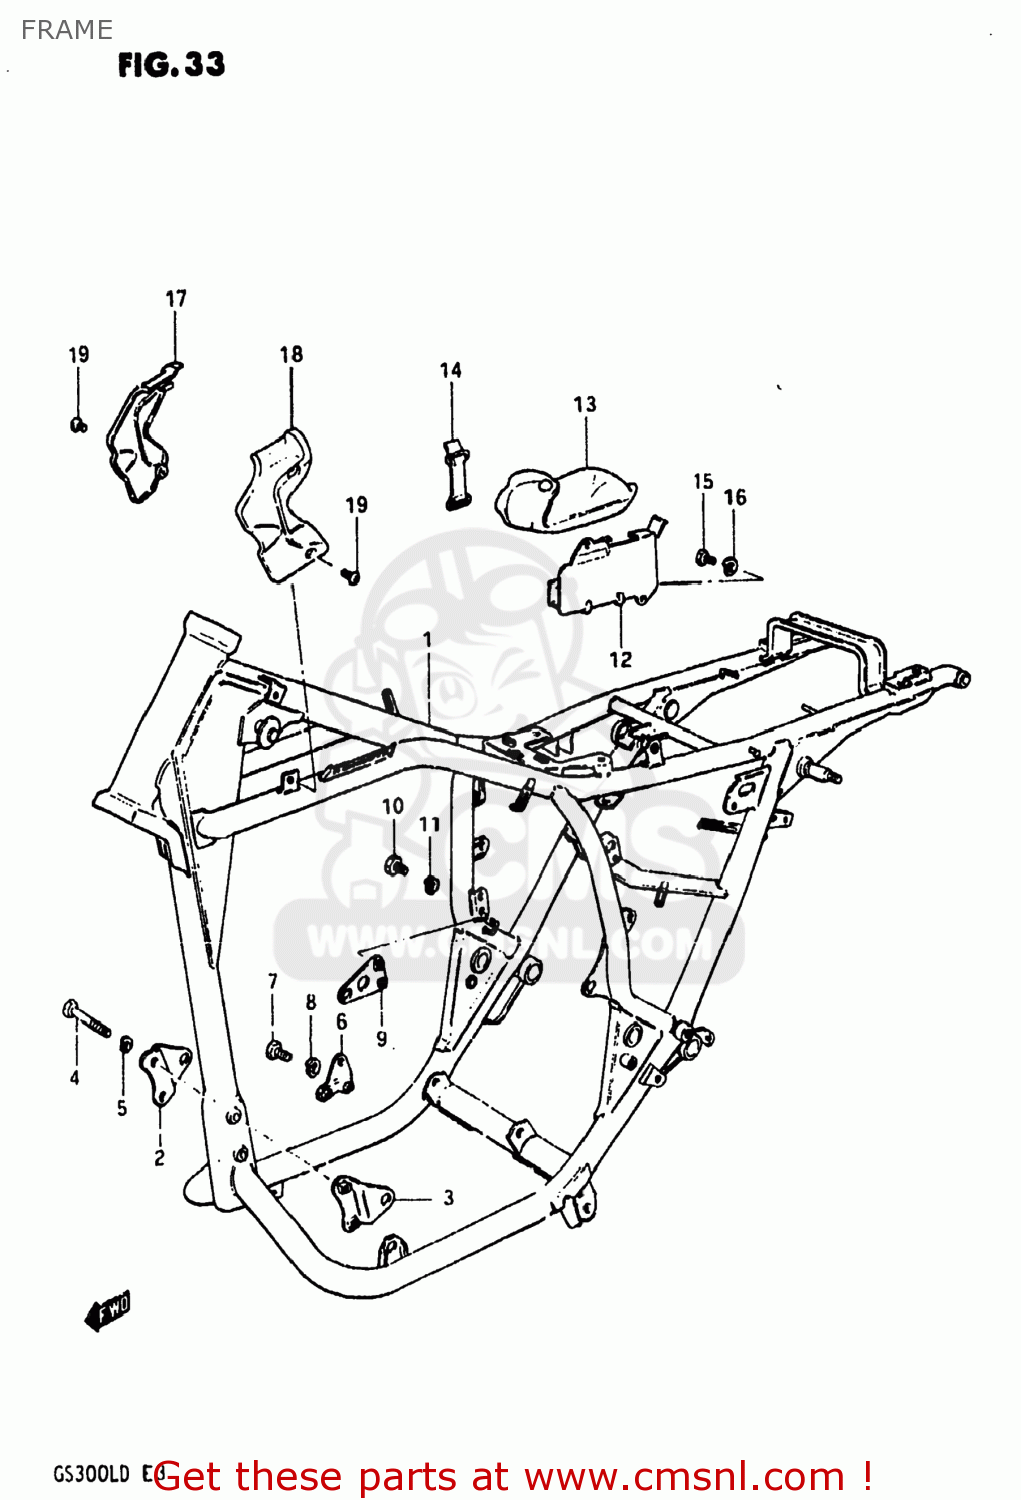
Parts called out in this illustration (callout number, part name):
1	FRAME
2	PLATE,MOUNTING NO.1,RIGHT
3	PLATE,ENGINE MOUNTING
4	BOLT
5	LOCK WASHER
6	PLATE,MOUNTING NO.2,LEFT
7	BOLT
8	LOCK WASHER
9	PLATE,MOUNTING NO.4,LEFT
10	BOLT
11	LOCK WASHER
12	HOLDER,TOOL
13	TOOL SET
14	BAND
15	BOLT
16	LOCK WASHER
17	COVER,FRAME HEAD,RIGHT
18	COVER,FRAME HEAD,LEFT
19	SCREW
